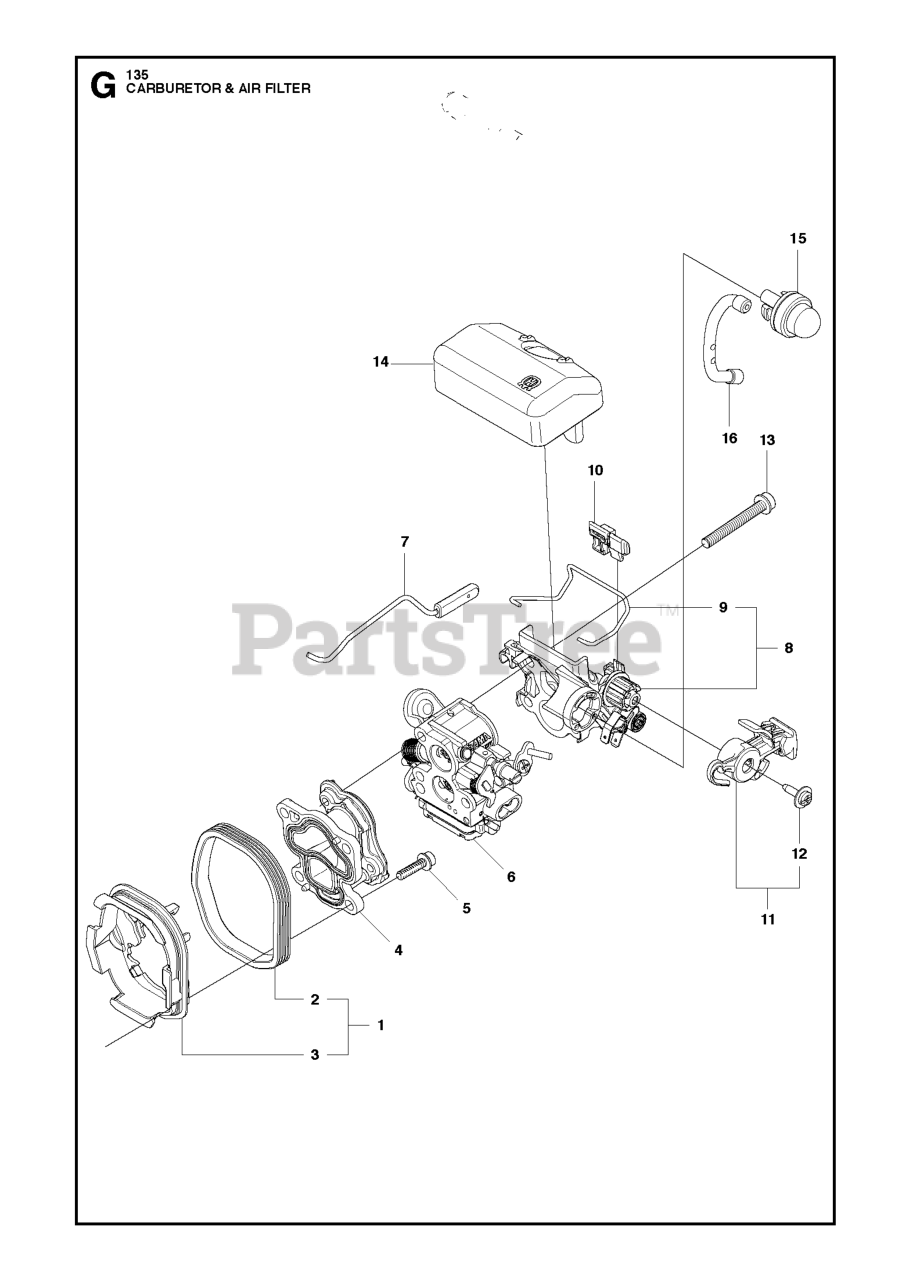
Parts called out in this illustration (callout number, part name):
1	INSULATION WALL
2	INSULATION WALL
3	INSULATION WALL
4	INLET PIPE
5	SCREW
6	CARBURETOR
7	THROTTLE ROD ASSY
8	ASSY FILTER HOLDER
9	SHACKLE
10	GUIDE
11	CONTROL
12	SCREW
13	SCREW
14	AIR FILTER
15	AIR PURGE BUBBLE
16	HOSE
